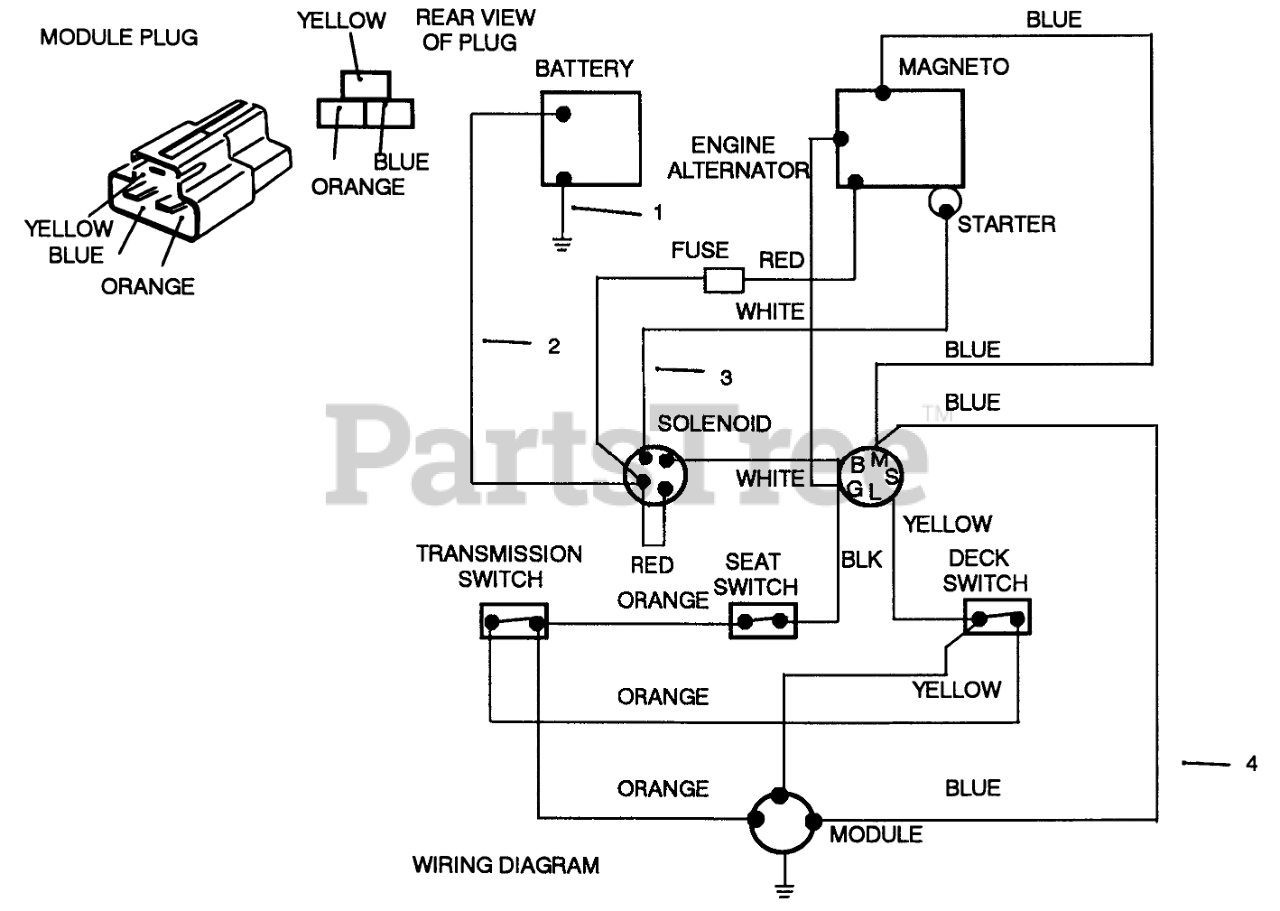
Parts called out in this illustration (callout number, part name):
1	WIRE ASM(BATT/GRD.
2	WIRE ASM
3	WIRE HARNESS
4	WIRING HARNESS
